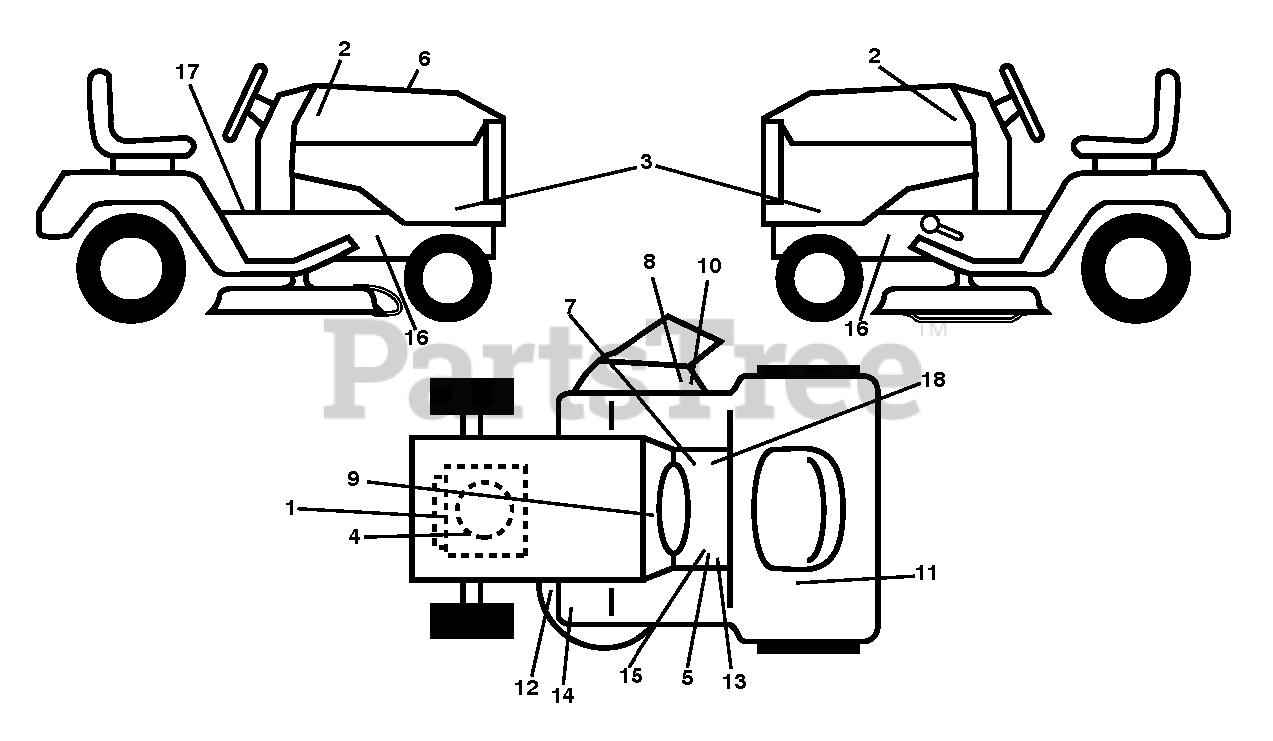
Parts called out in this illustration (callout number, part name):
1	DECAL, ENG. HP
2	DECAL.BADGE.170MM.TEXTLOGO.
3	DECAL DECAL.SDPNL.GT2.YTH2246
4	DECAL.ENGINE.WARNING
5	DECAL.80.DBA.AUSTRALIA
7	DECAL.FNDR.SDLE.BRAKE.CLUTCH.6
8	DECAL.CUTFINGER.CE.02
9	DECAL BTRY SYMBOLS
10	DECAL.DFLCTR.WARNNG.CTFNGR.SYM
11	DECAL.WARN.FUEL.RESERVE
12	DECAL.V-BELT.SCH.42/46"MEC/ELE
13	DECAL.READ.OWN.MAN.SYMBOL.LT
14	DECAL.PEDAL.HUSQ.CROWN
15	DECAL.TICKMARK.6MIL.AUSTRALIA
16	DECAL.CHASSIS.HOT.MUFFLER
17	DECAL.PARKING.BRAKE.SADDLE.LT
18	DECAL.PEDALS.SYMBOL
